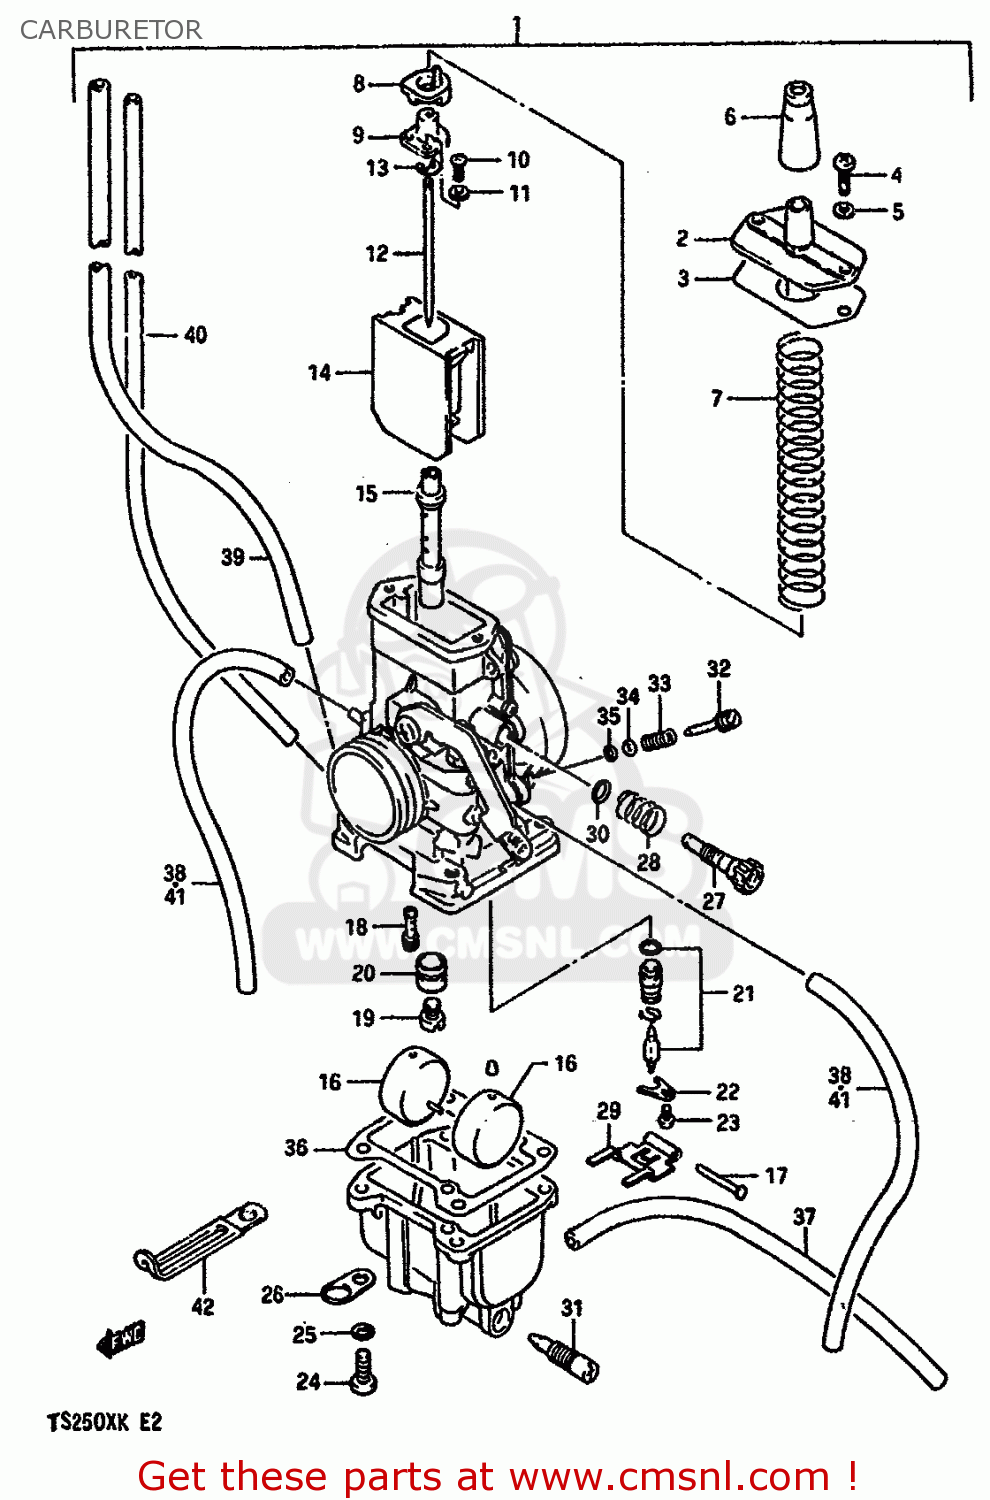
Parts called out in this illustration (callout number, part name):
1	CARBURETOR ASSY
2	CAP,TOP
3	GASKET,TOP (NAS)
4	SCREW
5	LOCK WASHER
6	CAP,CABLE ADJUSTER
7	SPRING
8	RING
9	JOINT
10	SCREW
11	LOCK WASHER
12	NEEDLE,JET (KHP24-3)
13	CLIP
14	VALVE,PISTON
15	JET,NEEDLE (P-4)
16	FLOAT
17	PIN,FLOAT
18	JET,PILOT (65)
19	JET,MAIN(125)
20	RING
21	VALVE ASSEMBLY,NEEDLE
22	PLATE
23	SCREW
24	SCREW
25	LOCK WASHER
26	PLATE
27	SCREW,THROTTLE STOP
28	SPRING,PILOT
29	ARM,FLOAT
30	O RING
31	PLUG,DRAIN
32	SCREW,PILOT AIR
33	SPRING,THROTTLE SCREW
34	WASHER
35	O RING,PILOT AIR SCREW
36	GASKET,FLOAT CAHMBER (NAS)
37	HOSE (3.5X6.5X150-80)
38	HOSE (3.5X6.5X150-80)
39	HOSE
40	HOSE
41	HOSE
42	CLAMP
